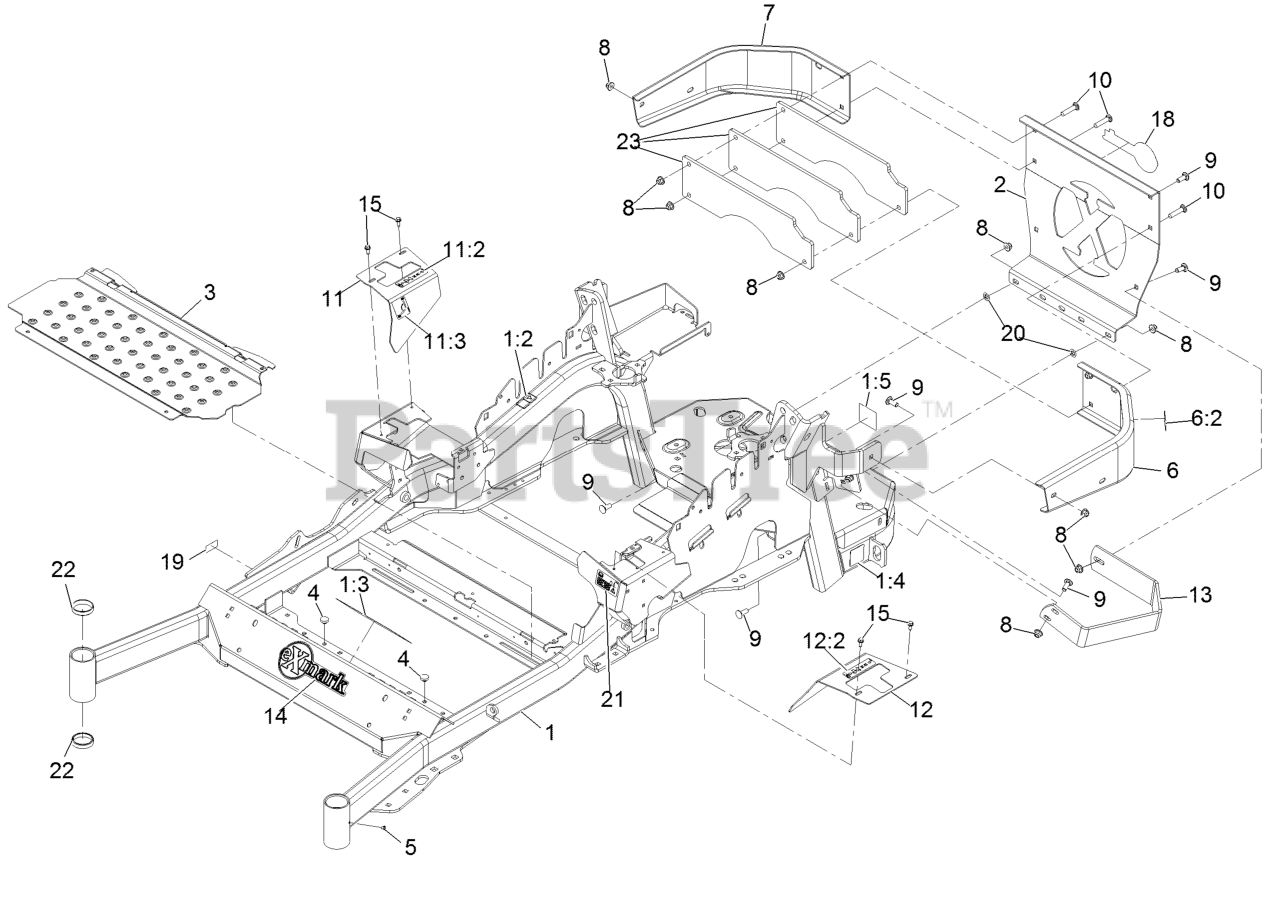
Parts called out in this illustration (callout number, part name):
1:2	DECAL-WARNING
1:3	DECAL-DANGER
1:4	DECAL-HAZARD, PINCHED FINGER
1:5	DECAL-SPARK ARRESTER
2	PLATE,REAR GUARD
6	LH BUMPER ASM
6:2	DECAL-WARNING
7	BUMPER-RH
8	NUT-HF, NI
9	SCREW-CARR
10	SCREW-CARR
11	RH MOTION CONTROL COVER ASM
11:2	DECAL-CONTROL, MOTION
11:3	DECAL-PARK BRAKE, CE
12	LH MOTION CONTROL COVER ASM
12:2	DECAL-CONTROL, MOTION
13	GUARD-MUFFLER
14	DECAL-EXMARK LOGO
15	SCREW-HWH
18	DECAL-EXMARK LOGO
19	Decal-Patent Ttco.Com
20	NUT-PUSH
21	DECAL-FUEL FILL, CE
22	CUP-BEARING
23	PLATE-WEIGHT, 6 LB
